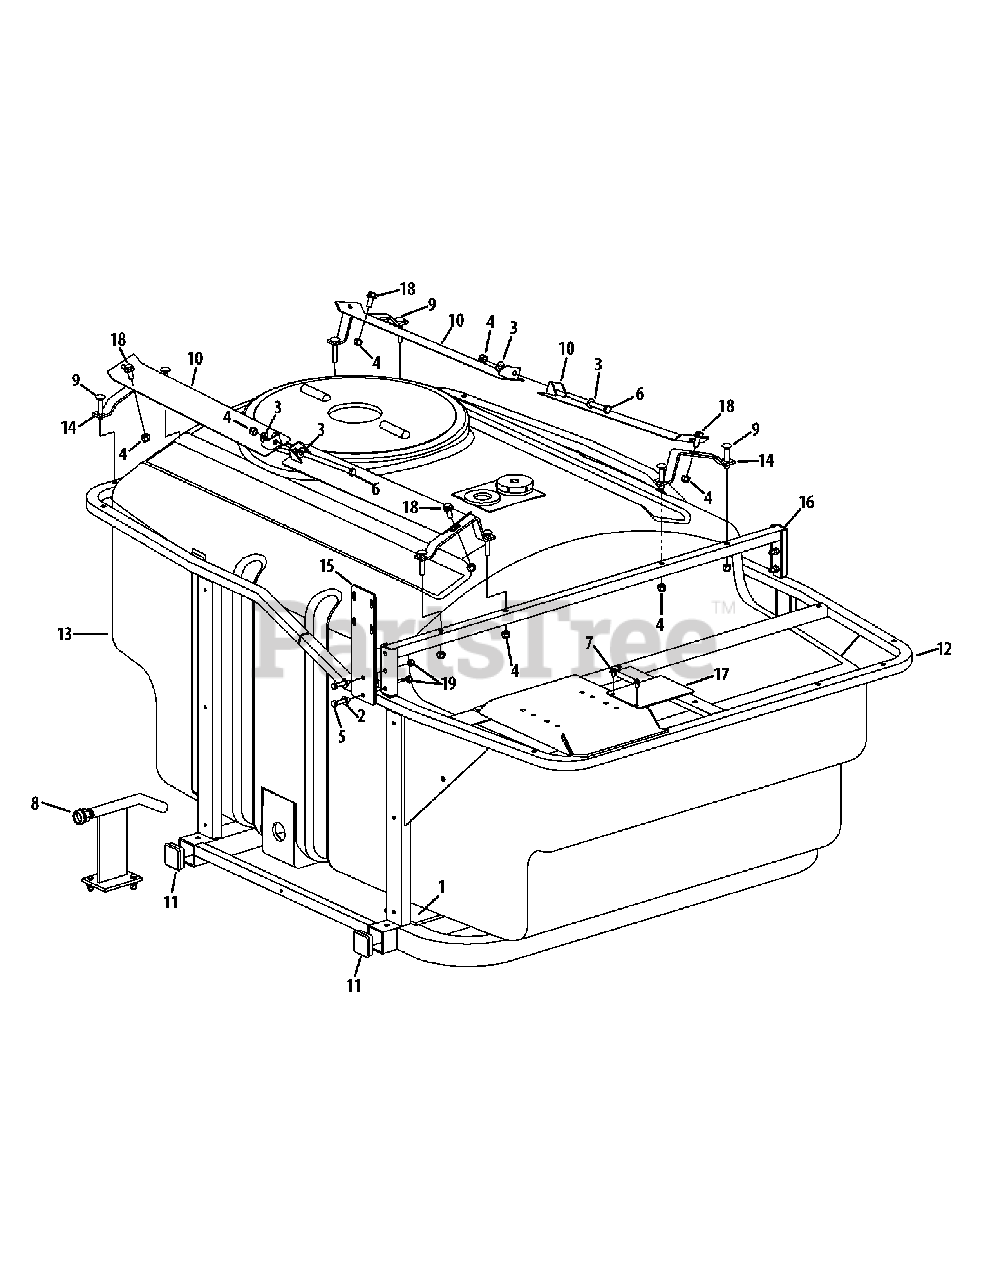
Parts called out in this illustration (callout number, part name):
1	Adhesive Backed Foam
2	Washer, .344 x .688 x .063
3	Washer, .406 x .813 x .063
4	Lock Nut, 3/8-16
5	Hex Screw, 5/16-18 x 1.50
6	Hex Screw, 3/8-16 x 5.00
7	Hex Flange Screw, 1/4-20 x .500
8	Air Gap Filler
9	Carriage Bolt, 3/8-16 x 2.0
10	Tank Strap
11	Square Tube Plug
12	Main Frame
13	Tank Assembly
14	Tank Strap Mount
15	Strainer Mount Bracket
16	Tank Strap Mount
18	Hex Screw, 3/8-16 x 1.00
19	Hex Lock Nut, 5/16-18
